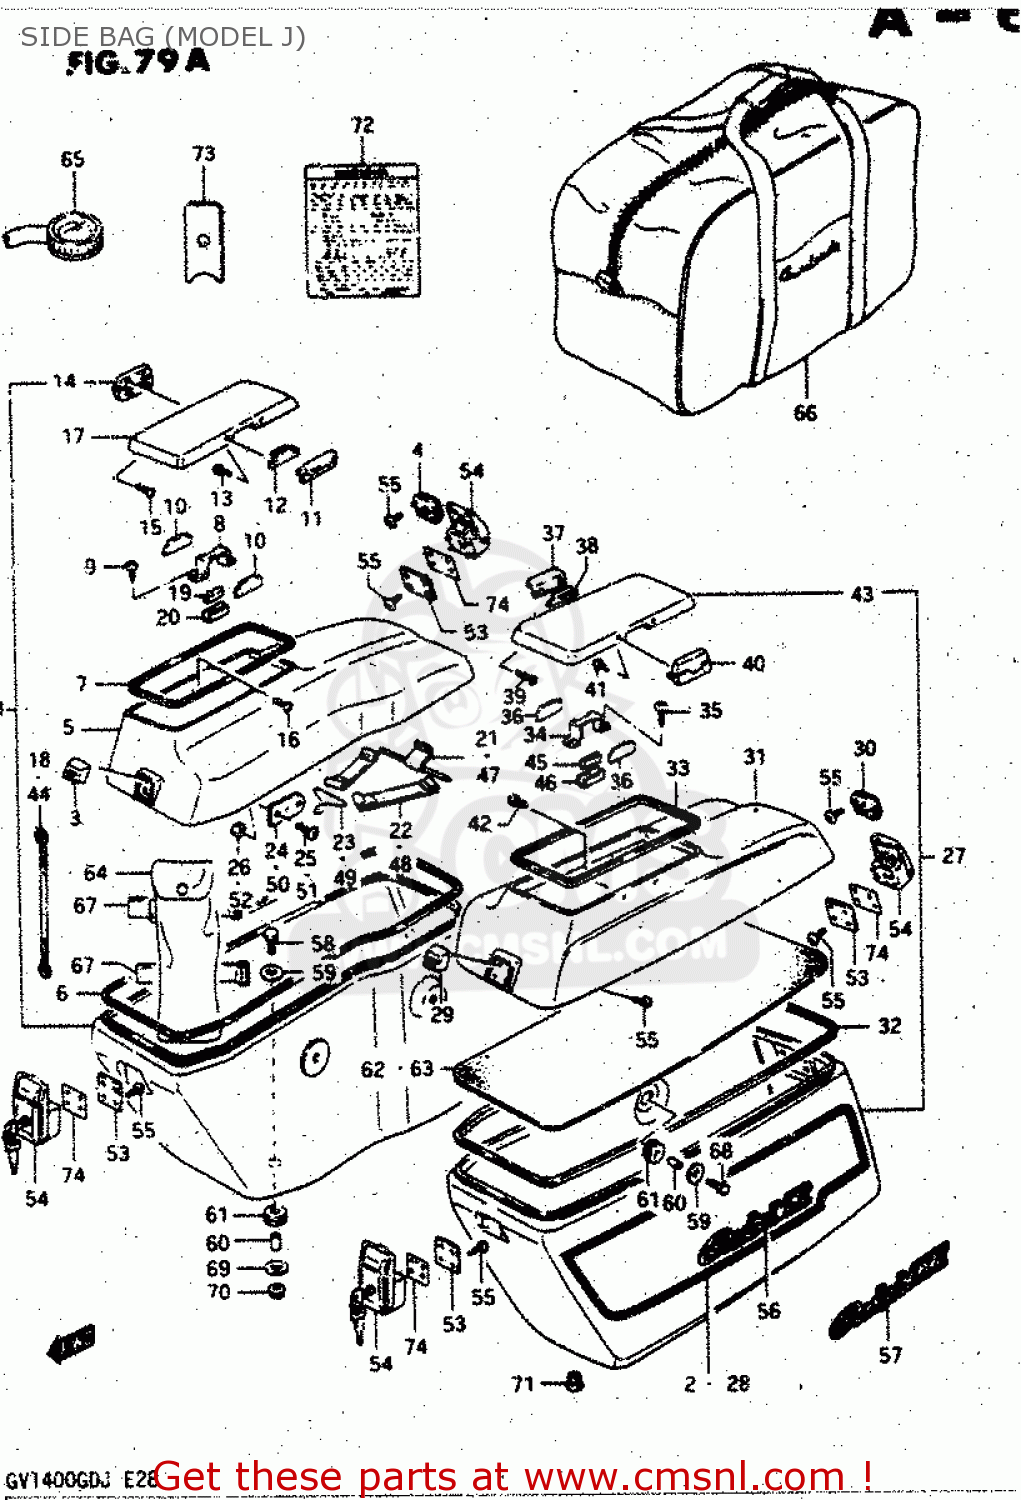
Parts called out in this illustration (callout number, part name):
1	BAG ASSEMBLY,SIDE,RIGHT
2	TAPE SET,SIDE BAG,RIGHT
3	PLATE,TRUNK LID LOCK
4	PLATE,SIDE BAG LID LOCK
5	LID,SIDE BAG,RIGHT
6	SEAL,SIDE BAG
7	SEAL,SIDE BAG
8	HOLDER,LID LOCK MAGNET
9	SCREW
10	PLATE,LID LOCK
11	LEVER,SIDE POCKET OPEN
12	PLATE,LID LOCK NO.1
13	SCREW
14	HINGE,LID SIDE BAG POCKET
15	SCREW
16	SCREW
17	LID,SIDE BAG POCKET
18	BAND,SIDE BAG LID
19	MAGNET
20	BOX, HOLDER
21	PLATE,LUGGAGE BAND LID
22	BAND,LUGGAGE LID
23	.HOOK
24	PLATE, FRONT
25	SCREW, FRONT & REAR
26	NUT 5MM
27	SIDE BAG ASSEMBLY,LEFT
28	TAPE SET,SIDE BAG STRIP
29	PLATE,TRUNK LID LOCK
30	PLATE,SIDE BAG LID LOCK
31	LID,SIDE BAG,LEFT
32	SEAL,SIDE BAG
33	SEAL,SIDE BAG
34	HOLDER,LID LOCK MAGNET
35	SCREW
36	PLATE,LID LOCK
37	LEVER,SIDE POCKET OPEN
38	PLATE,LID LOCK NO.1
39	SCREW
40	HINGE,LID SIDE BAG POCKET
41	SCREW
42	SCREW
43	LID,SIDE BAG POCKET
44	BAND,SIDE BAG LID
45	MAGNET
46	BOX, HOLDER
47	PLATE,LUGGAGE BAND LID
48	BAND,LUGGAGE LID
49	.HOOK
50	PLATE, FRONT
51	SCREW, FRONT & REAR
52	NUT 5MM
53	SET PLATE,LOCK SIDE BA
54	LOCK ASSY, SIDE BAG
55	SCREW
56	EMBLEM,SIDE BAG,RIGHT
57	EMBLEM
58	BOLT 6X30
59	WASHER (6.5X29X1.6)
60	SPACER(6.3X9.3X16.5)
61	CUSHION
62	SEAT, BOTTOM RH
63	SEAT, BOTTOM LH
64	TOOL ASSY
65	GAUGE ASSY,AIR PRESSURE
66	LUGGAGE BAG,SIDE BAG
67	BAND
68	BOLT(6X30)
69	WASHER (6.5X18X2)
70	NUT
71	CAP(OD:12)
72	LABEL (WARNING TRAVEL T
73	SPANNER
74	PACKING SEAT
